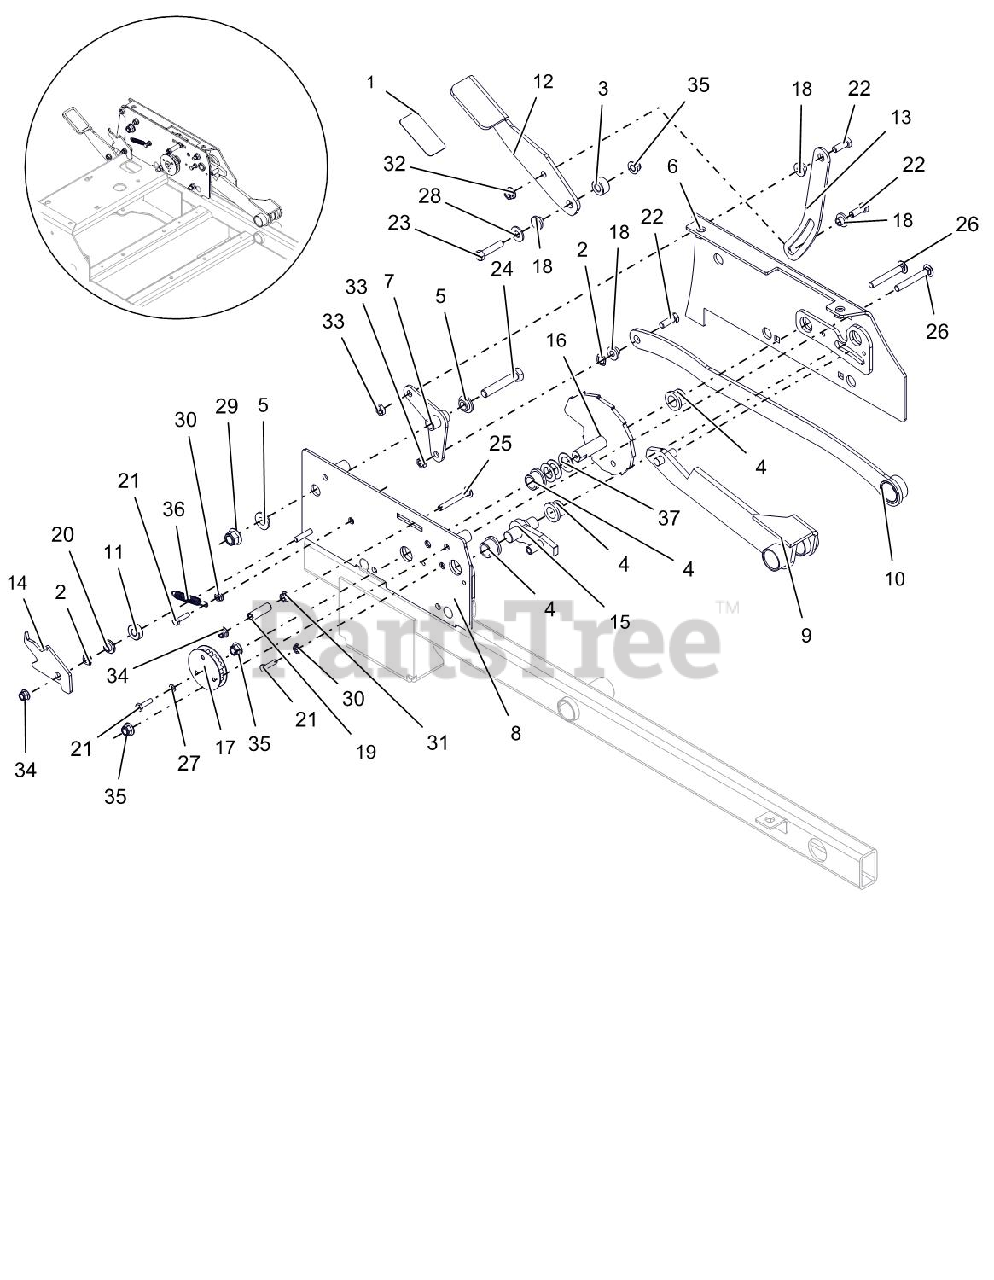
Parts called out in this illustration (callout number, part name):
1	GRIP, PEDAL 1.50 X 3.00
2	WAVE WASHER .531X.781X.125FH
3	SPACER, .437X1.00X.58 SMLS
4	BUSHING, FLANGE .75X.75X1.0
5	BSHG-FLG .515X.750X.310X1.120
6	SIDE, LH BOTTOM TOWER
7	WLDMT, REAR PIVOT
8	WLDMT, CAM COVER
9	WLDMT, CAM CONTACT
10	WLDMT, DECK LIFT LINK
11	SPCR, .375 X 1.00 X .342
12	PEDAL, DECK LIFT
13	LINK, DECK LIFT PEDAL
14	LATCH, FOOT PEDAL
15	WLDMT, DECK LOCK
16	WLDMT, HEIGHT OF CUT
17	WLDMT, LOWER PULLEY
18	BSHG-FLG .385X.500X.875X.406
19	BSHG-SLV .325X.49X1.56
20	BSHG-FLG .32X.500X.344X.880
21	@BLT-HEX .25-20X1.00 GR5 YWZC
22	@BLT-HEX .38-16X1.00 GR5 YWZC
23	@BLT-HEX .38-16X1.75 GR5 YWZC
24	@BLT-HEX .50-13X2.75 GR5 YWZC
25	@BLT-RDHDSQNK .31-18X2.50 G5YZ
26	@BLT-RDHDSQNK .38-16X2.75 G5YZ
27	@WSHR-LK .25X.062 REG YWZC
28	@WSHR-FL-STL.438X1.00X.083 YWZ
29	@NUT-LK-NYL-FLG .50-13 YWZC
30	@NUT-SPNLK-FLG .25-20 YWZC
31	@NUT-SPNLK-FLG .312-18 YWZC
32	NUT-LK-CTR-FLG .38-16 YWZC
33	@NUT-LK-CTR-JAM .375-16 YWZC
34	@NUT-LK-NYL-FLG .31-18 YWZC
35	@NUT-LK-NYL-FLG .38-16 YWZC
36	SPRING, EXTENSION
37	WSHR-FL-STL .750X1.250X.048 YZ
